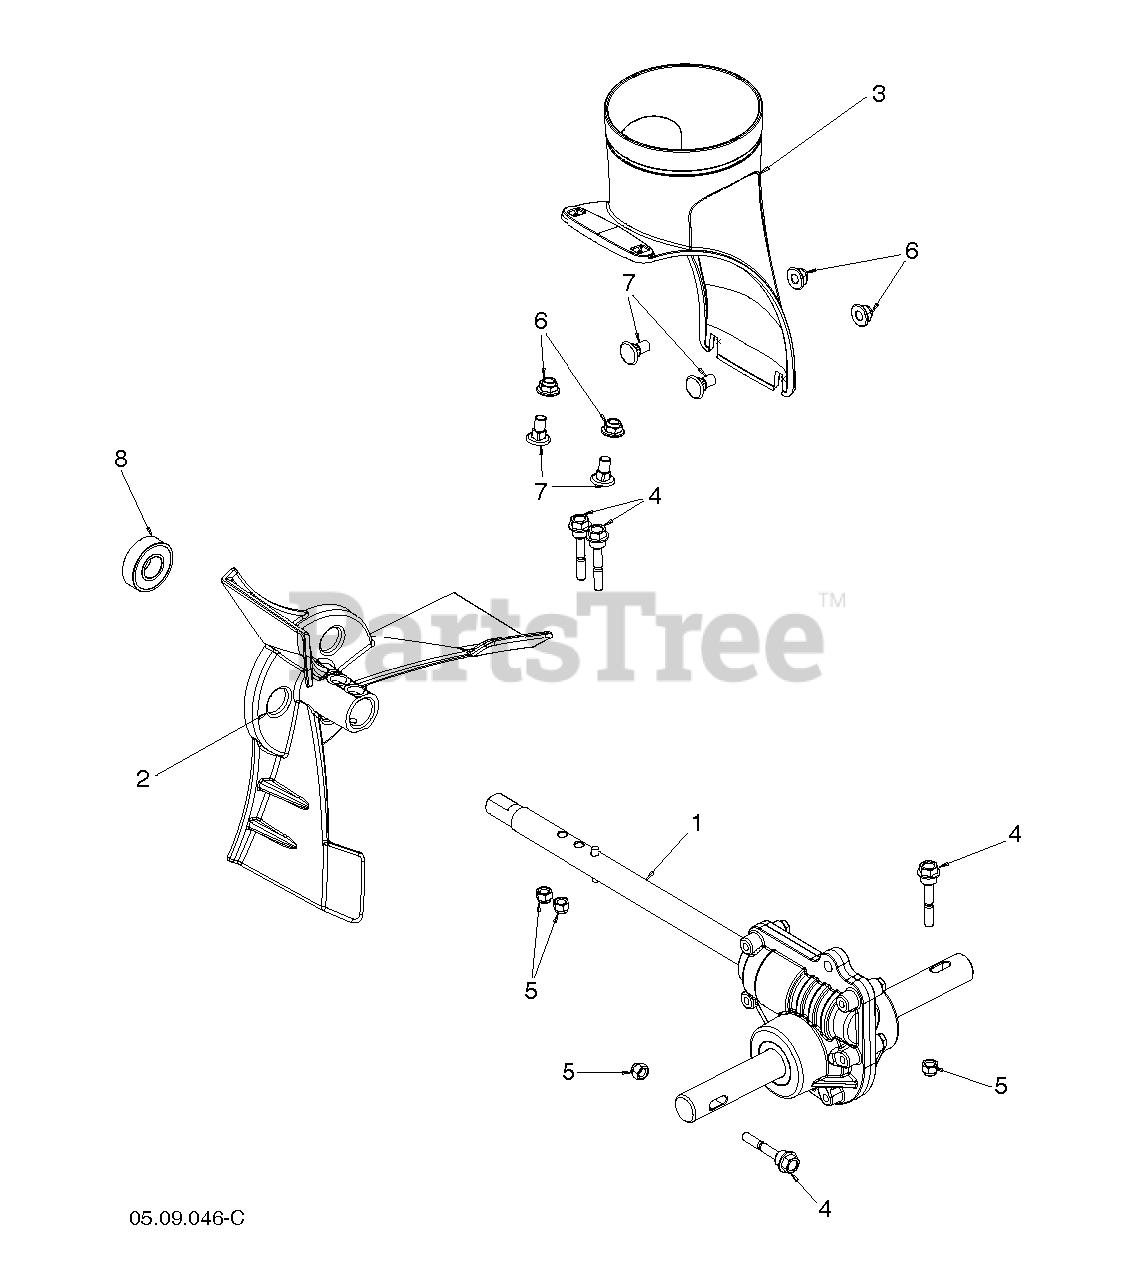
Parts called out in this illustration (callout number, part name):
1	GEARBOX CAST DD SHAFT
3	CHUTE BASE CAST ALUM HUSQ SIL
4	BOLT SHEAR HX HD 1/4-20 CLEAR
5	NUT HEXAGON 1/4-20 ST ZPB
6	NUT HEX FLG NYLOCK BLK 5_16-1
7	BOLT CARR WAFER BLK 5_16-18 X
